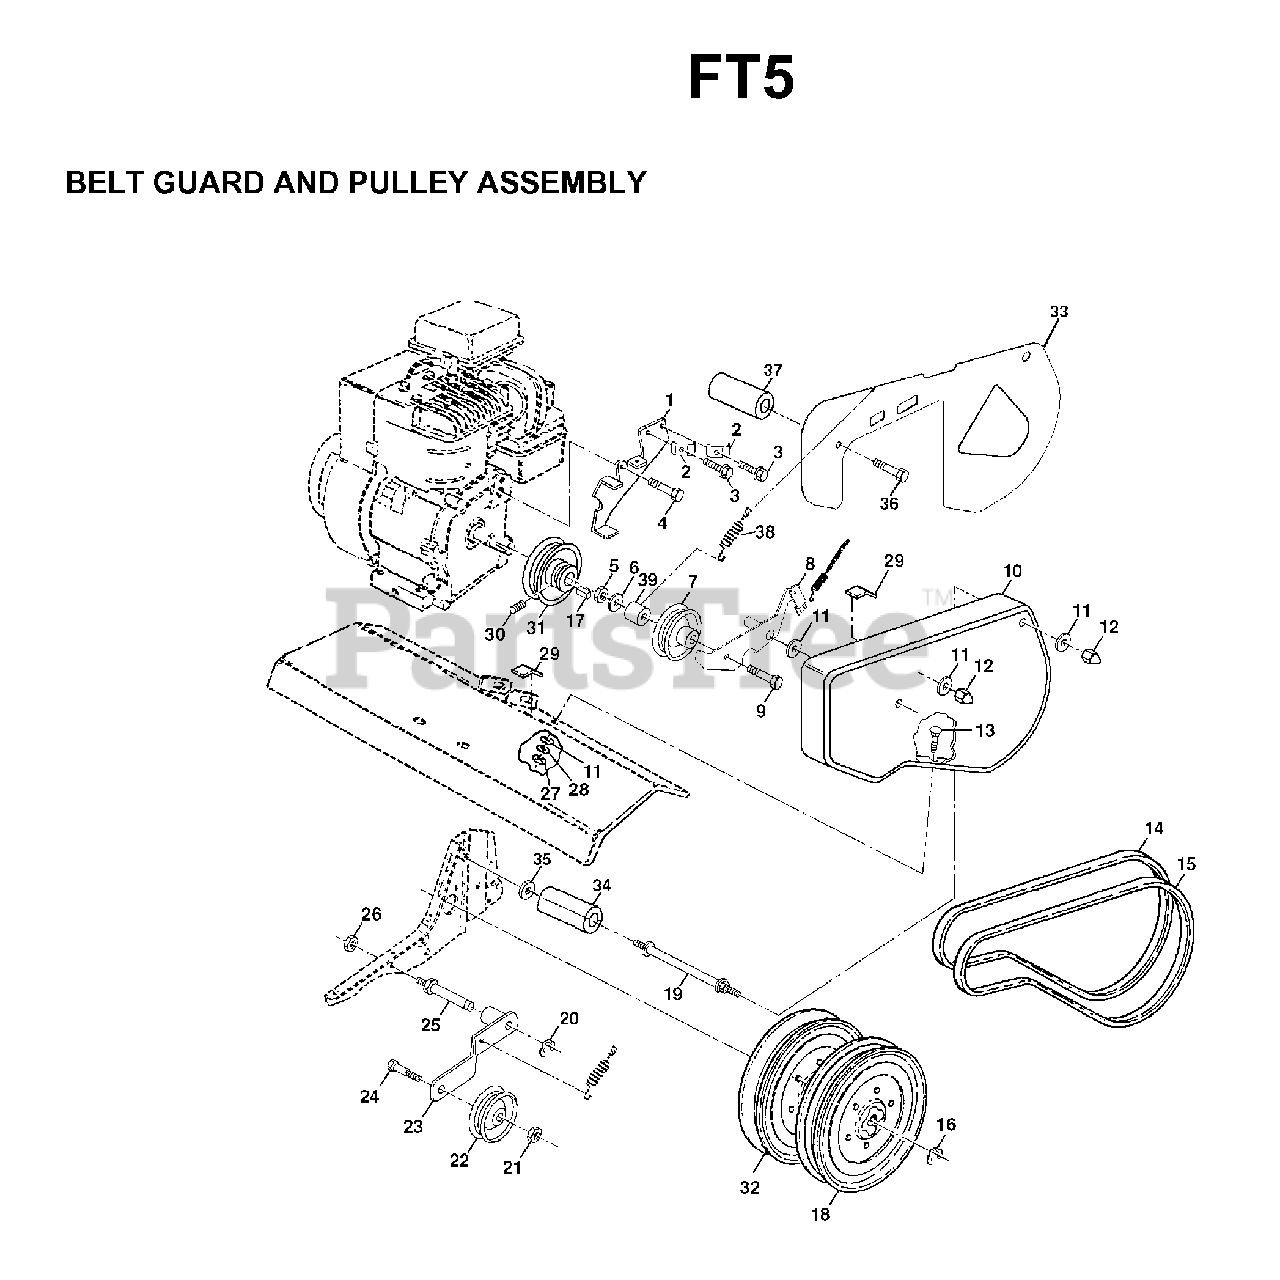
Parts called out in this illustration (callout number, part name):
2	CONDUIT CLIP T
3	TAPPING SCREW
7	PULLEY
8	ARM
9	BOLT
11	WASHER
12	CAP
16	RETAINING RING LT
18	SHEAVE,TRANS."D"
20	KLIP RING TI
21	NUT
22	FLAT IDLER
25	SHAFT.IDLER.TILLER
26	JAM NUT TI
27	NUT
28	LOCKWASHER
29	PAD IDLER TI
32	SHEAVE.TRANS
38	SPRING.EXTENSION
